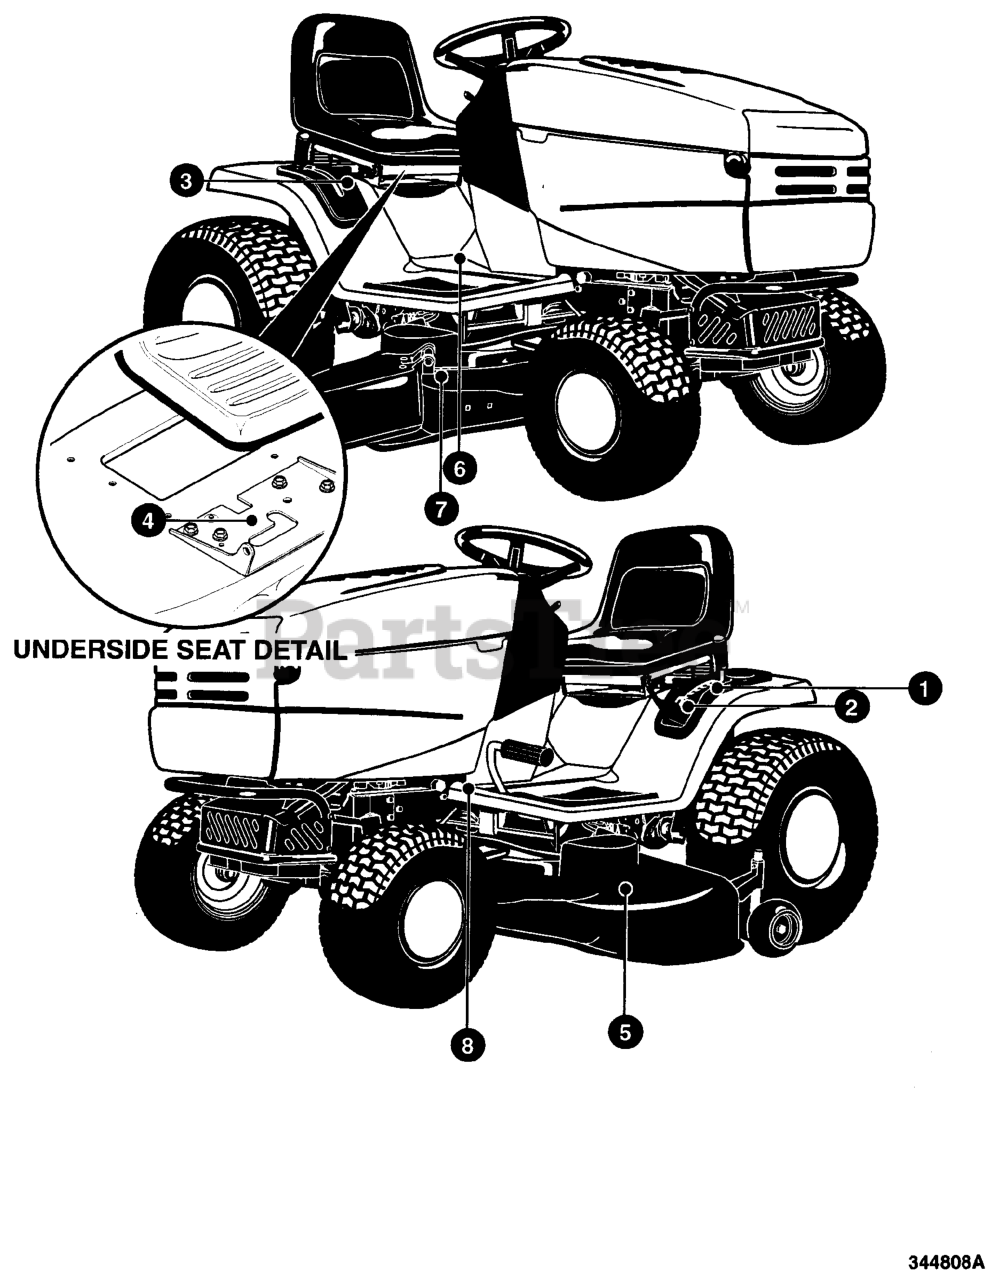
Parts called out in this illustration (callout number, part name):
1	DECAL, HEIGHT ADJUST 1-6
2	DECAL, DECK LEVEL
3	DECAL, CRUISE CONTROL
4	DECAL, HYDRO REL. VALVE
5	DECAL, NO STEP
6	DECAL, INSTRUCTIONS CONSOLE
7	DECAL, DOM CUT FINGER/OPEI98
8	DECAL, CLUTCH/BRAKE TOE
